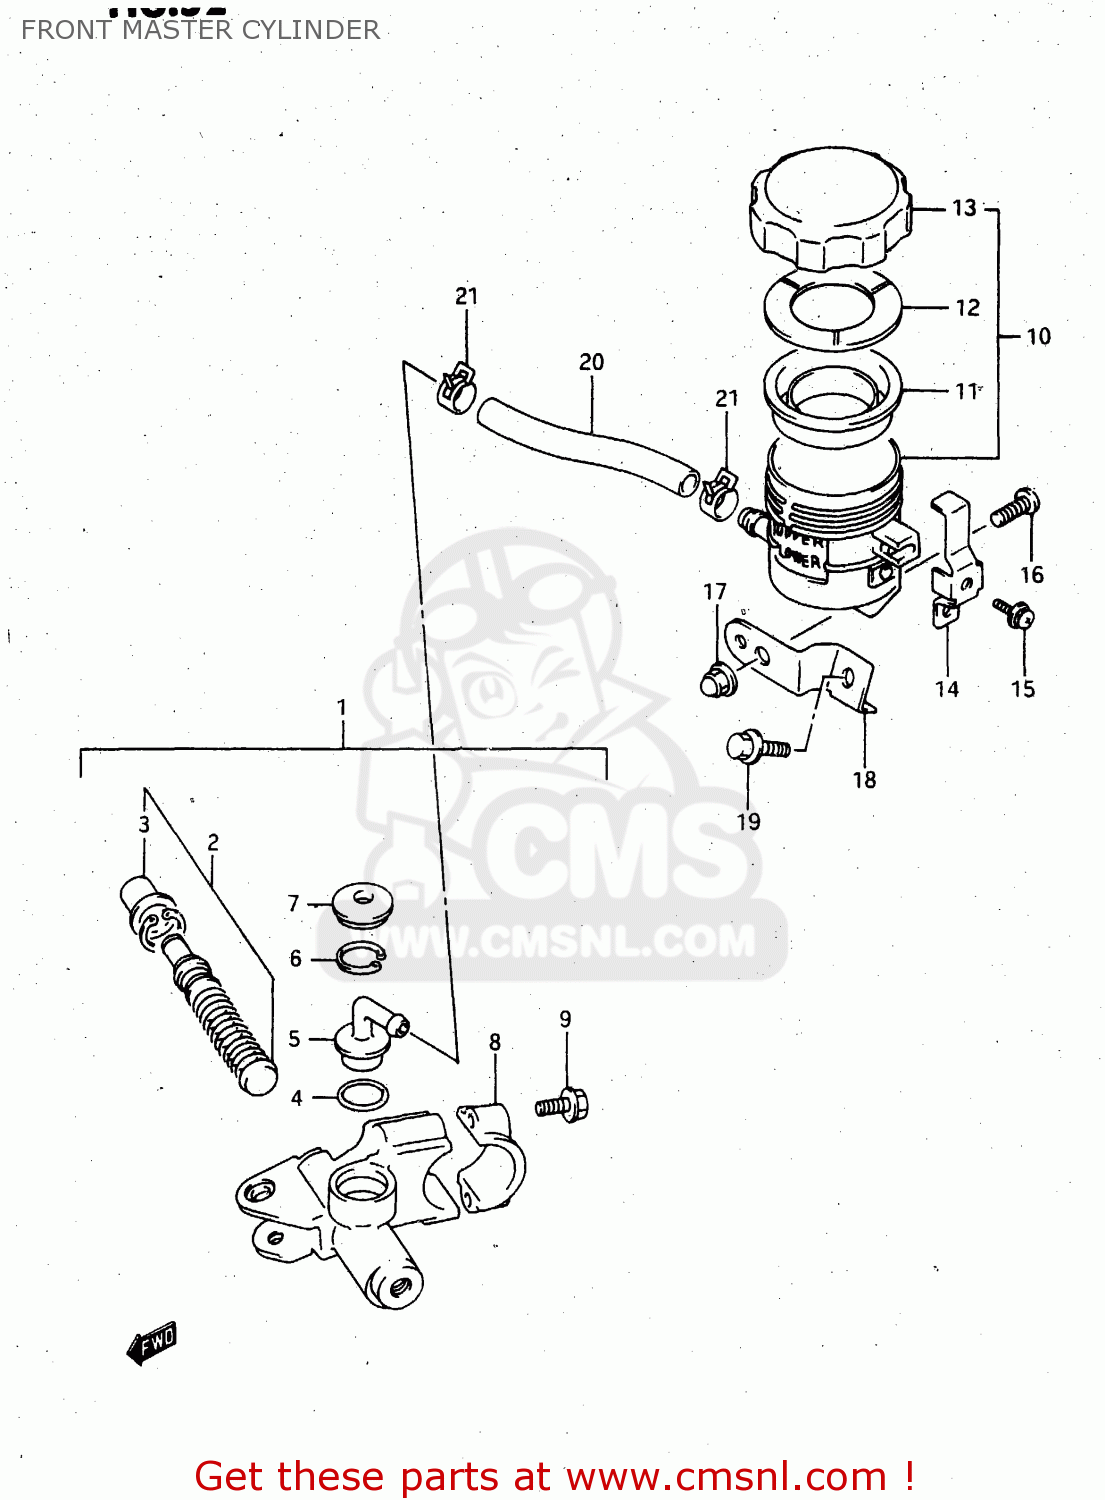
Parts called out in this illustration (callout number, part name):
1	CYLINDER ASSY,FR MASTER
2	PISTON & CUP SET
3	BOOT
4	O RING
5	CONNECTOR
6	CIRCLIP
7	COVER,DUST
8	HOLDER
9	BOLT
10	TANK ASSY,RESERVOIR
11	DIAPHRAGM
12	PLATE,DIAPHRAGM
13	CAP
14	PLATE,RESERVOIR TANK CAP
15	SCREW
16	SCREW
17	NUT
18	BRACKET,FR RESERVOIR TANK
19	BOLT
20	HOSE,FR RESERVOIR TANK
21	CLAMP,RESERVOIR TANK FR
